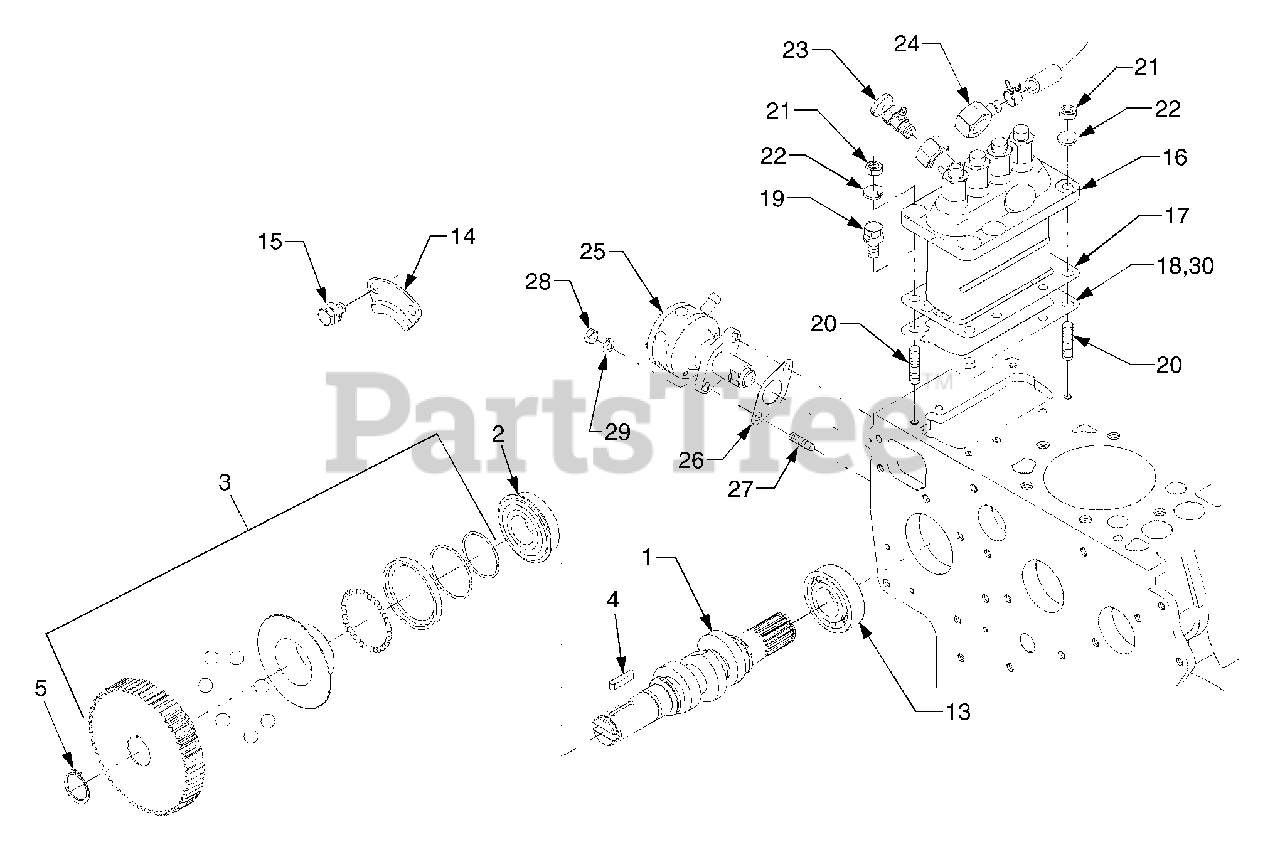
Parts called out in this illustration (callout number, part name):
1	Fuel Camshaft
2	Bearing, Ball
3	Governor Sleeve Ass'y
13	Bearing, Ball
14	Stopper, Fuel Camshaft
16	Injection Pump Ass'y
17	Shim, Injection Pump
18	Shim, Injection Pump
22	Washer, Spring
23	Jet Start Cock Ass'y
24	Joint, Fuel Pipe
25	Fuel Pump Ass'y
26	Gasket, Fuel Pump
29	Washer, Spring
30	Shim, Injection Pump
